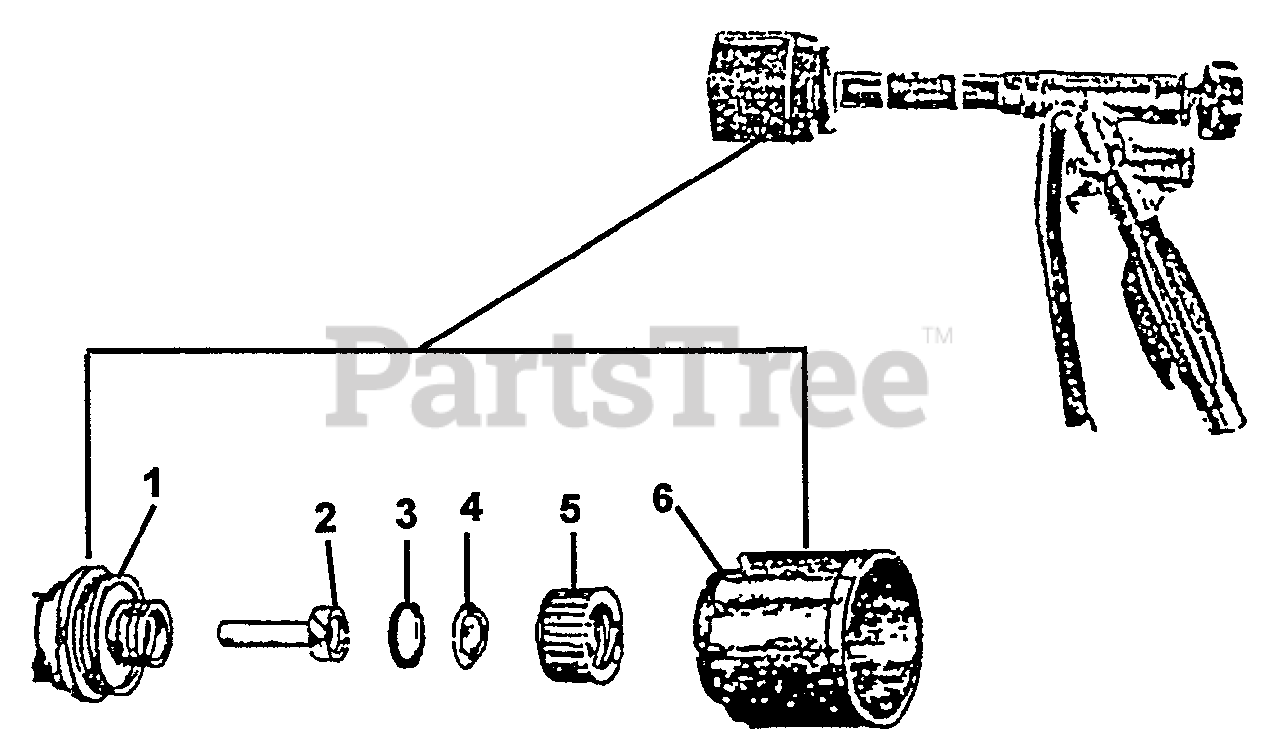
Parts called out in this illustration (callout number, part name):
1	NOZZLE BODY
2	ZOOM CORE
4	PLATE, NOZZLE
5	CAP
